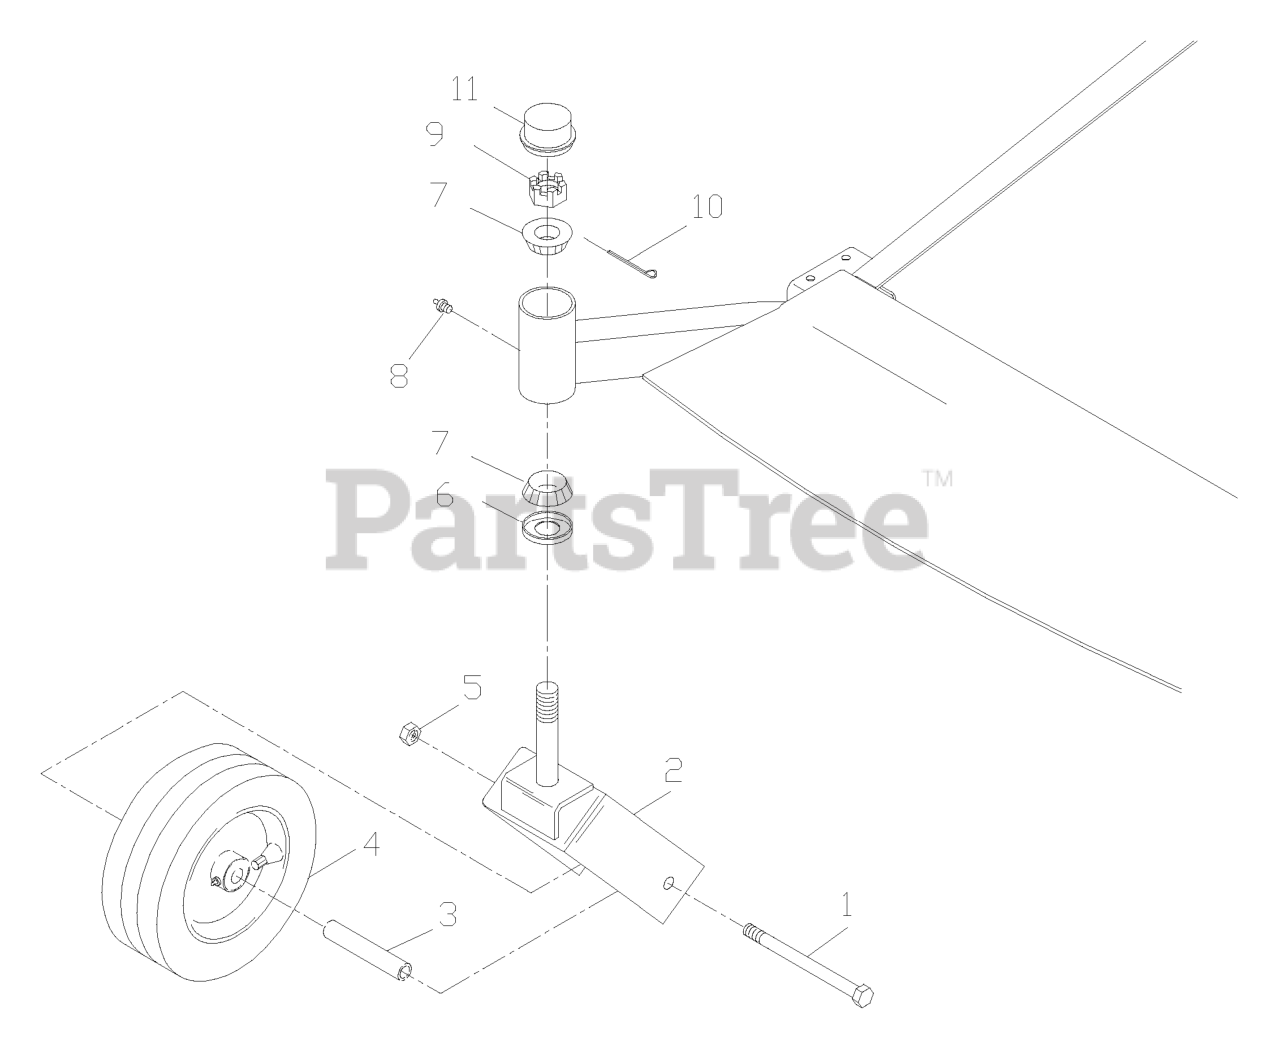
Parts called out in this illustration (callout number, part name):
1	SCREW 1/2C X 7 1/2 HEX CAP
2	CASTER YOKE ORANGE
3	SPACER, CASTER
4	TIRE.ASSEM.13X5-6.SMOOTH.SILVE
4	TIRE - FRONT
4	RIM
4	ROLLER BEARING
4	BEARING RETAINER
4	VALVE STEM TR-412
5	NUT 1/2-13 HEX NYLOC ZD
7	BEARING W/CUP
9	NUT 1"C HEX SLOTTED
10	COTTER PIN 1/8 X 2
11	GREASE CAP
